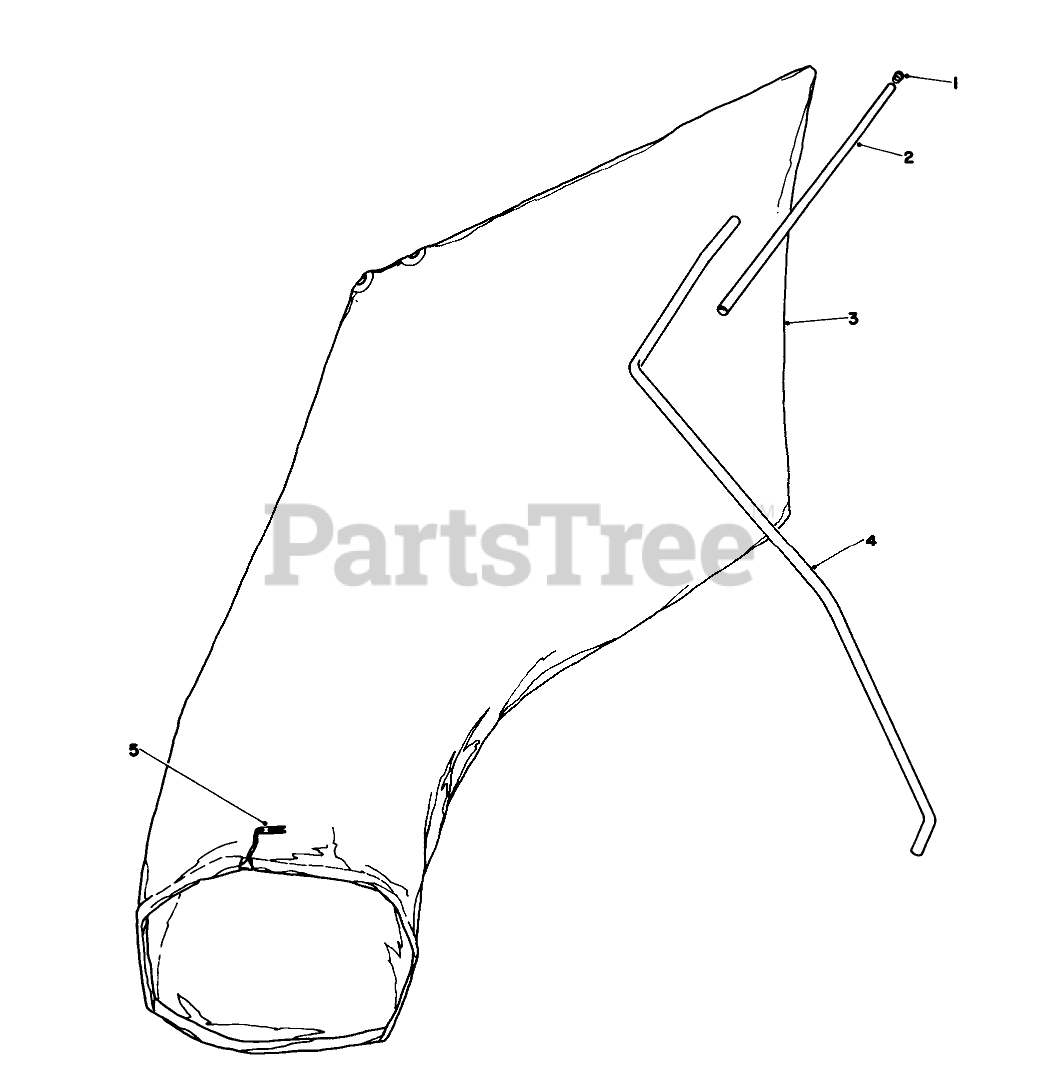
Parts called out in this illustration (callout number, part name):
2	BAG HANGER TUBE
3	Bag (Incl. Ref. #5)
4	HANGER ROD
5	BAG CORD FASTENER
